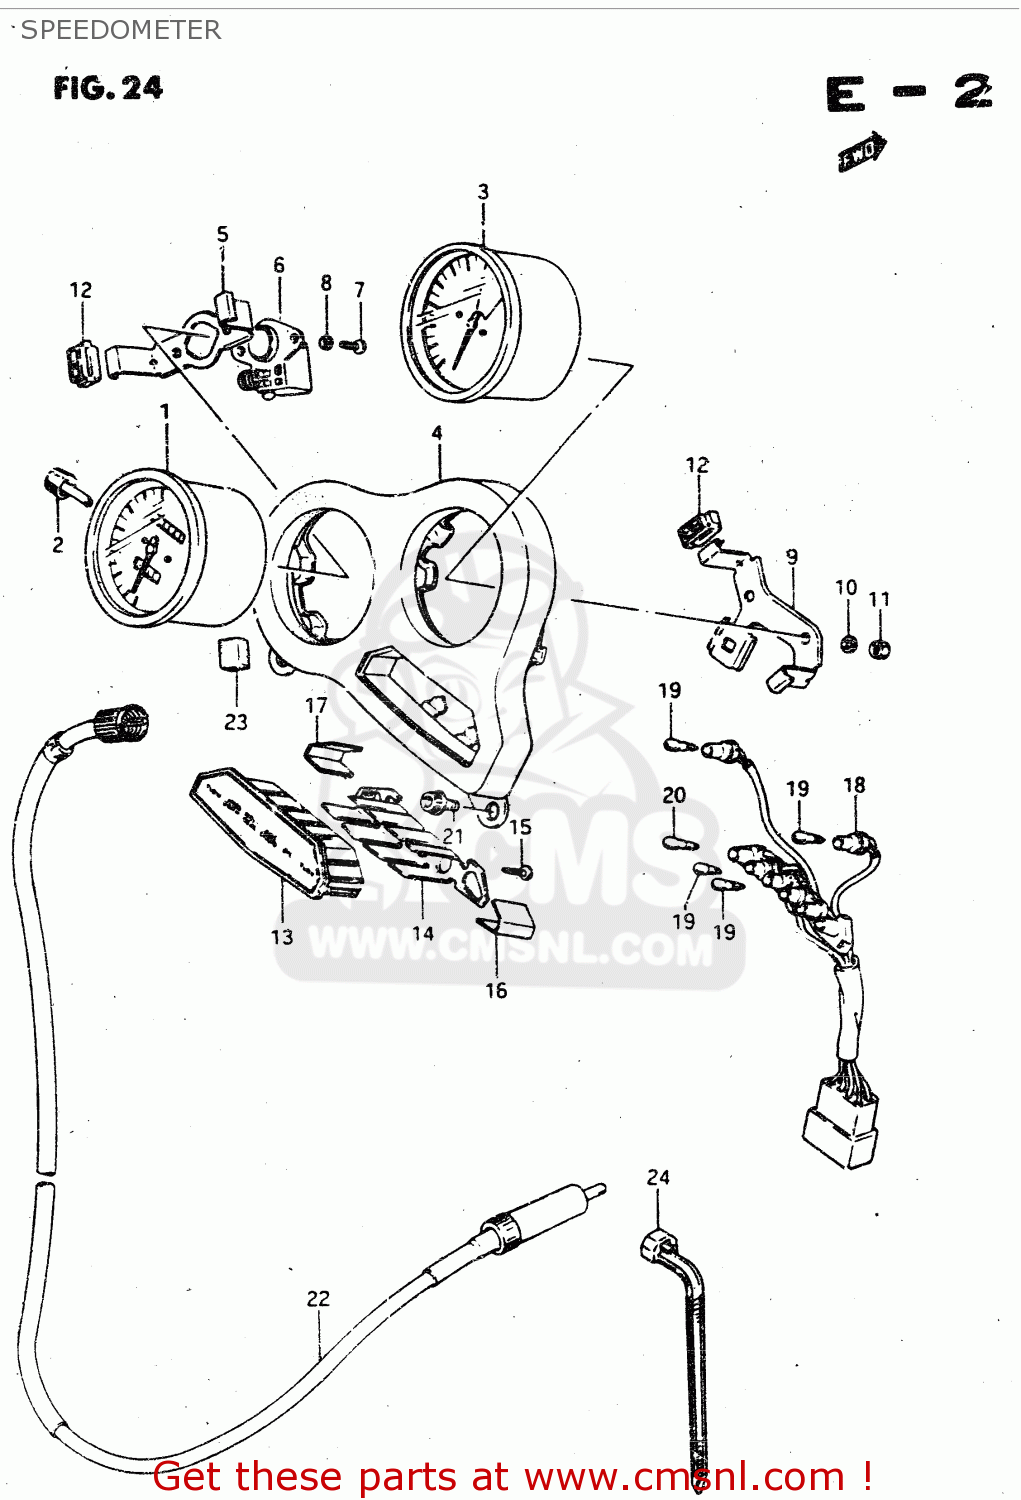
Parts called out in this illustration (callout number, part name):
1	SPEEDOMETER (KILO)
2	KNOB,TRIP
3	TACHOMETER
4	BRACKET, METER
5	PLATE,SPEEDOMETER
6	BOX,METER GEAR
7	SCREW
8	LOCK WASHER
9	PLATE,TACHOMETER
10	WASHER
11	NUT
12	CUSHION
13	CASE, PILOT LAMP
14	PLATE,PILOT LAMP
15	SCREW
16	PLATE,TURN,R
17	PLATE,TURN,L
18	SOCKET
19	BULB(12V3W,WB371,T7)
20	BULB(12V1.7W,WB372,T7)
21	BOLT
22	CABLE ASSEMBLY,SPEEDOMETER
23	CUSHION,METER
24	CLAMP(L:95)
